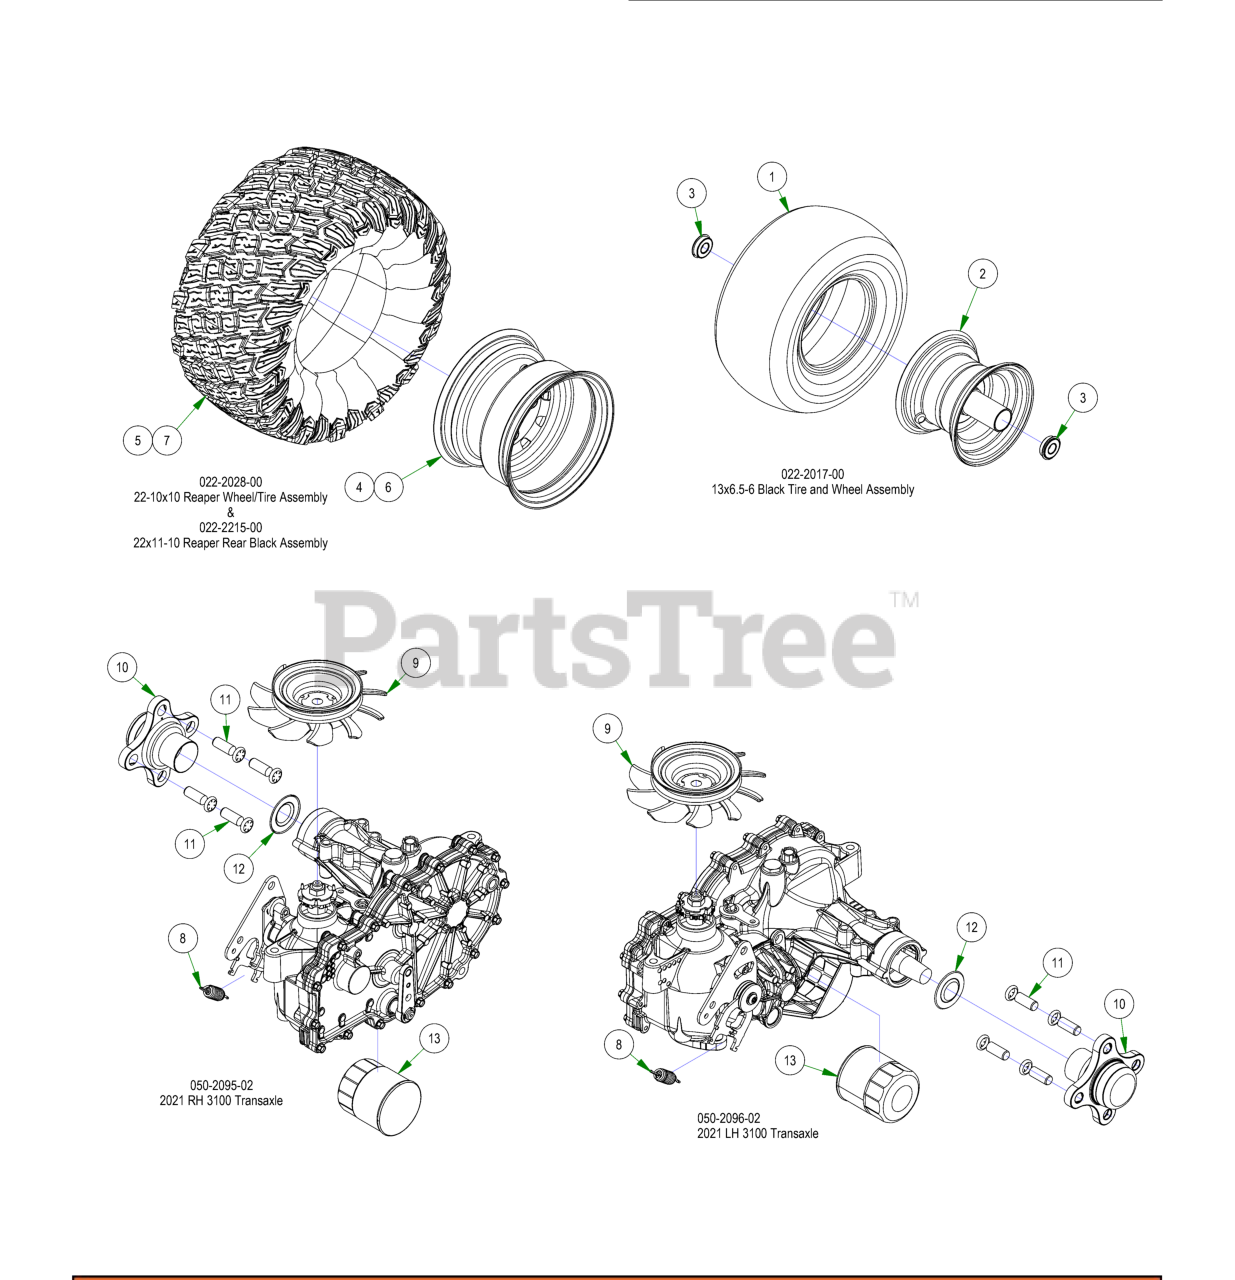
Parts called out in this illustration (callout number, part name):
1	13 x 6.50 - 6 Tire
2	Front Tire Rim
3	Ball Bearing w/Retainer, 99502H-NR, .625 Bore x 1.375 OD x .4375 Width
4	WHEEL, 10", BLACK
5	22-10x10 Reaper Tire Only
6	ZT Wheel Only 22x11-10
7	22x11-10 Reaper Rear TIRE ONLY
8	Gold Transaxle Spring
9	2021 ZT/Maverick Transaxle Fan/Pulley Kit
10	ZT Transaxle Wheel Hub
11	Transaxle Wheel Studs/ Drum Brake Studs
12	2021 ZT/Maverick Transaxle Seal Kit (ZT-2800)
13	ZT Hydraulic Filter
